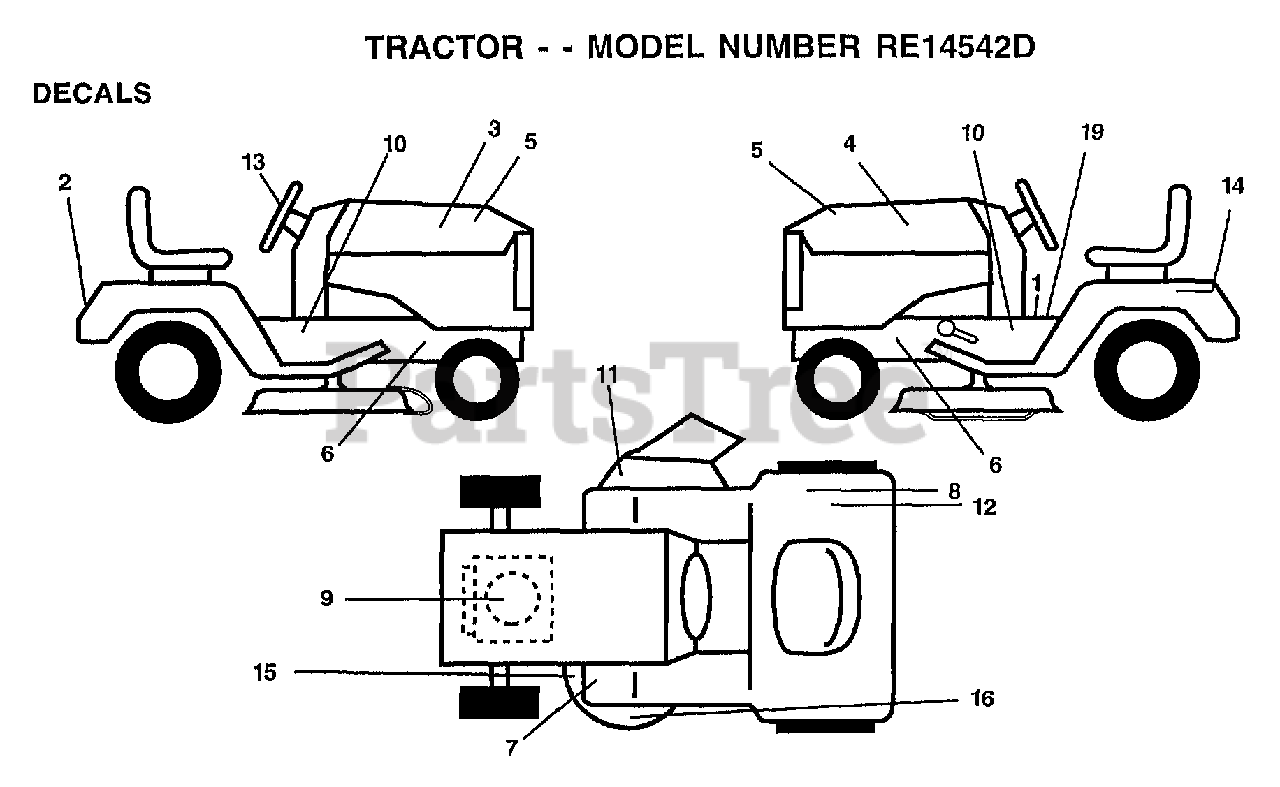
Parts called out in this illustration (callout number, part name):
1	DECAL.READ.O.MANU
2	FENDER DECAL
3	DECAL HOOD RH
4	DECAL HOOD LH
5	DECAL.INS.HD.RALL
6	"DECAL CHASSIS,HOT"
7	DECAL-BRAKE/CLUTC
8	DECAL.EURO.ST.CE.
9	DECAL, HP ENGINE
10	CHASSIS DECAL
11	DECAL.DANGER.CUTF
13	"DECAL,STR WHL"
14	DECAL.BATRY.3-3908
15	"DECAL-SCHEM,BELT"
19	DECAL BRAK PARK
